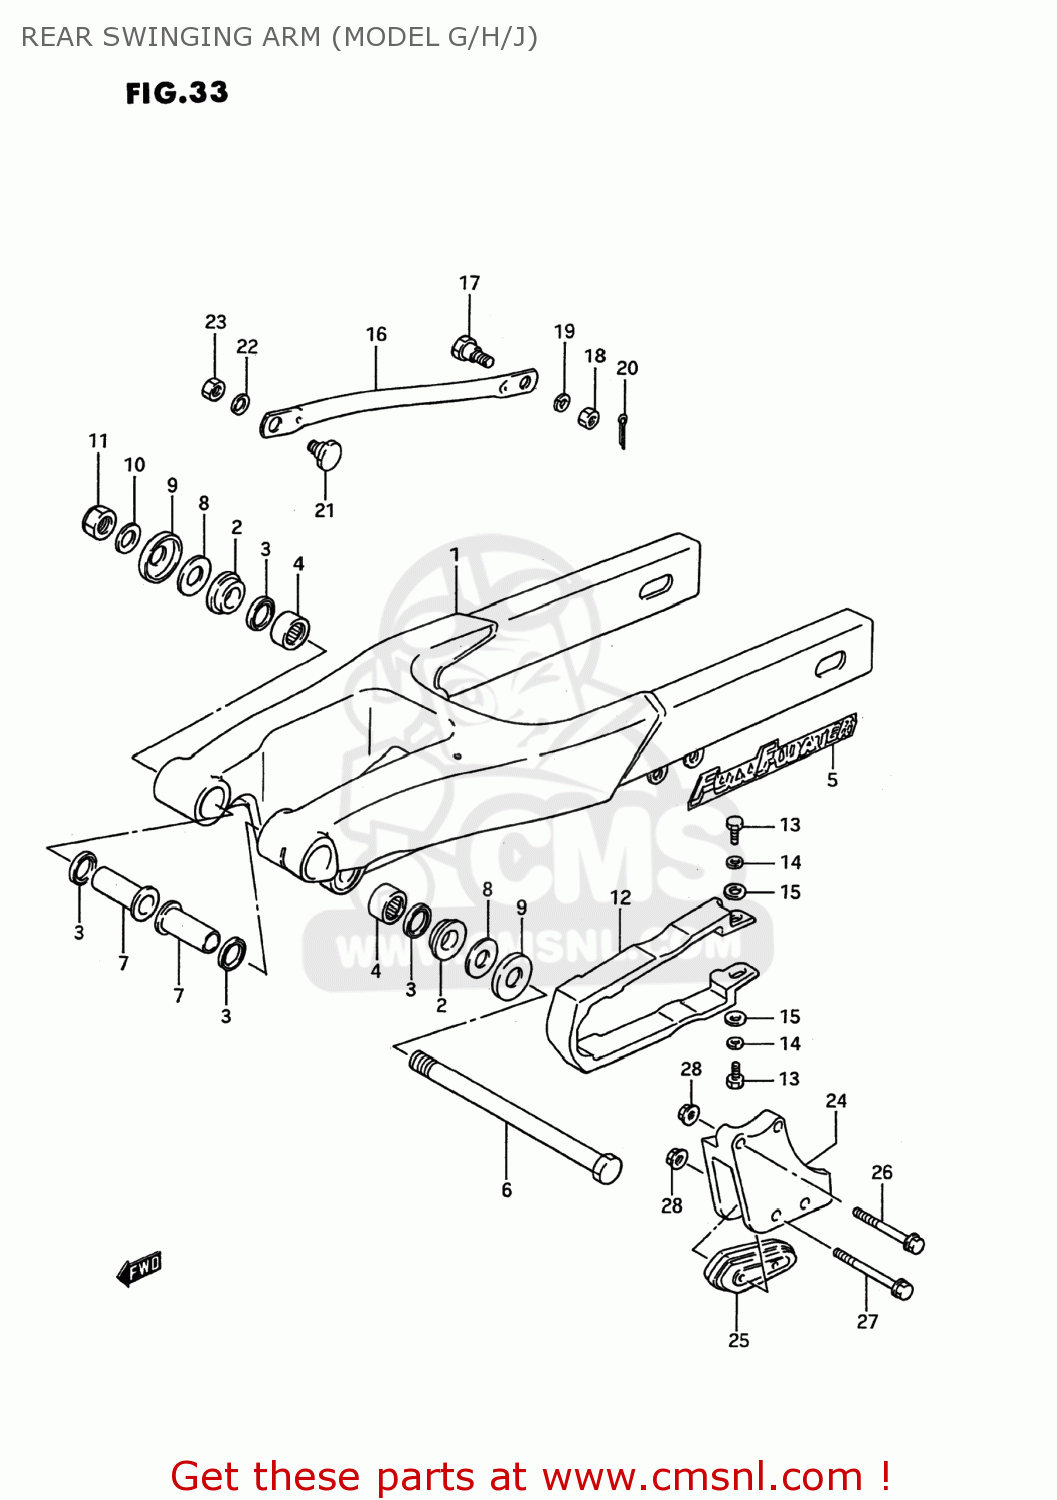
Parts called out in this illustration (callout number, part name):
1	SWING ARM ASSEMBLY,REAR
2	BUSHING,SWGARM PIVOT
3	SEAL,OIL(17X24X3)
4	ROLLER BEARING (17X24X25)
5	EMBLEM,SWING ARM
6	SHAFT,REAR SWING ARM PIVOT
7	SPACER,RR SWGARM PIVOT
8	WASHER
9	COVER,REAR SWING ARM DUST
10	WASHER
11	NUT 12MM
12	BUFFER,CHAIN TOUCH DEFENSE
13	BOLT
14	WASHER,LOCK
15	WASHER(6.5X16X1.2)
16	TORQUE LINK
17	BOLT(8X21)
18	NUT
19	LOCK WASHER
20	PIN 20X20
21	BOLT(8X21)
22	WASHER
23	NUT
24	GUIDE,CHAIN
25	DEFENSE,CHAIN GUIDE
26	BOLT 6X35
27	BOLT,UNDER
28	NUT
